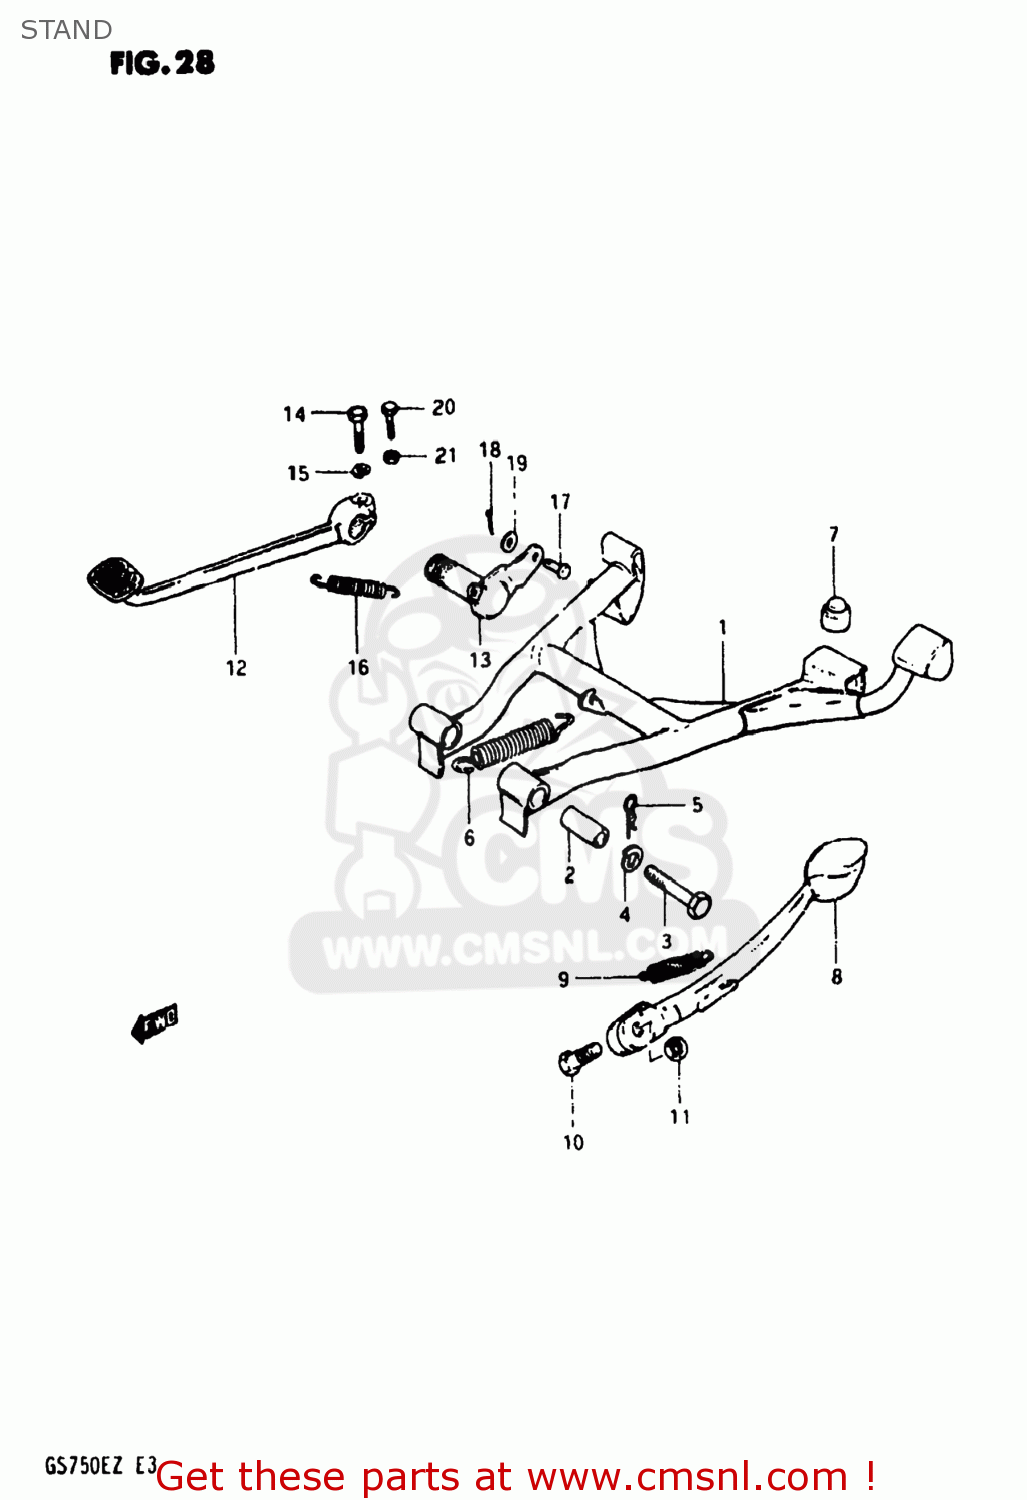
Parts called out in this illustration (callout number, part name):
1	STAND,CENTER
2	SPACER(10X16X38.8)
3	BOLT
4	LOCK WASHER
5	CLIP
6	SPRING
7	CUSHION
8	STAND,SIDE
9	SPRING
10	BOLT(10X30)
11	NUT
12	PEDAL,BRAKE
13	ARM,BRAKE PEDAL ROD
14	BOLT
15	LOCK WASHER
16	SPRING
17	PIN
18	PIN
19	WASHER
20	BOLT
21	NUT
